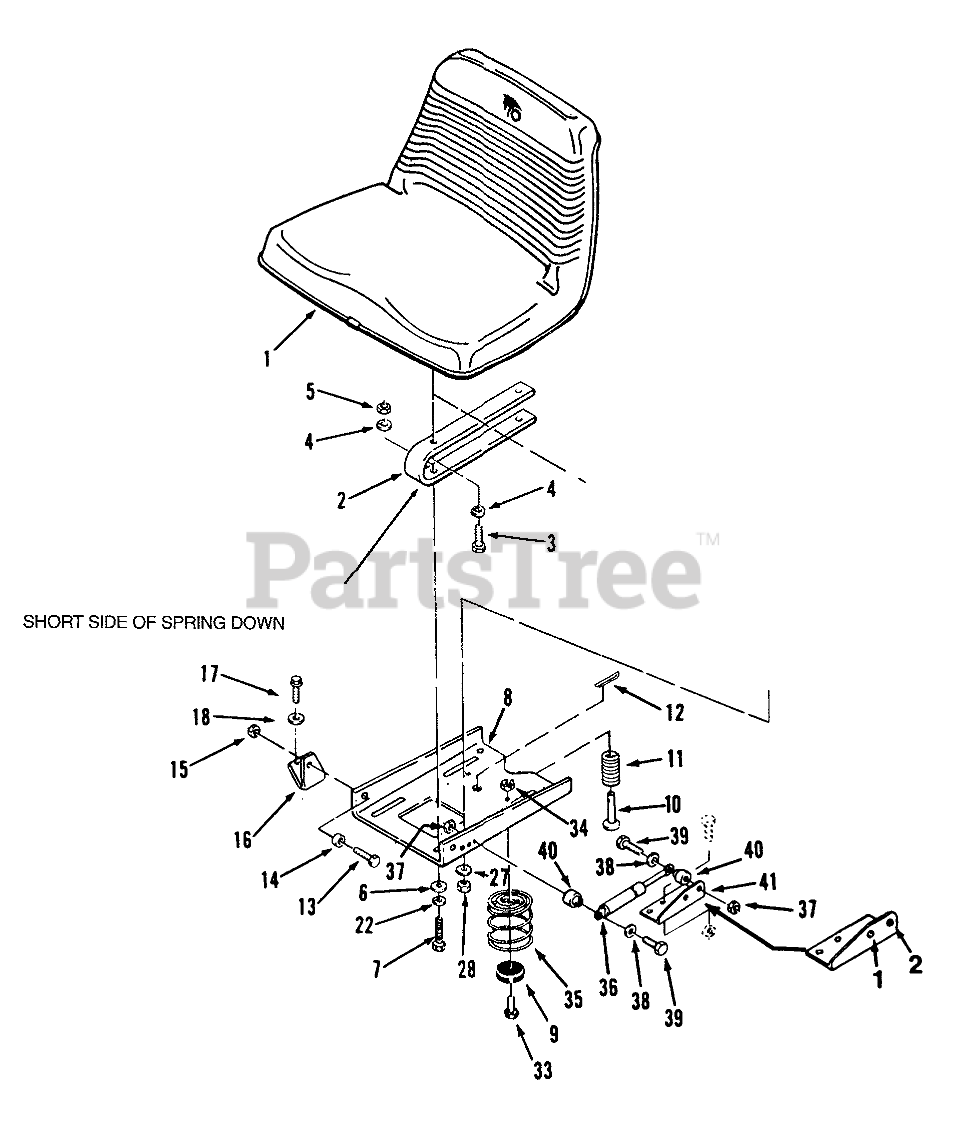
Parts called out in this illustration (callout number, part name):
1	Seat
2	Seat Spring
3	SCREW
4	Lockwasher
5	Nut
6	WASHER 5/16 SAE
7	HHCS
8	PLATE-SEAT PIVOT B
9	BUMPER
11	SPRING-SEAT SWITCH
12	Cotter Pin
13	HHCS
14	BUSHING
15	Nut
16	Bracket-Pivot RH
17	Bolt
27	Collar
28	Nut
33	Bolt
34	Nut
35	SPRING
36	GAS SPRING
37	Nut
39	Bolt
40	SPACER
41	BRACKET-CYLINDER R
